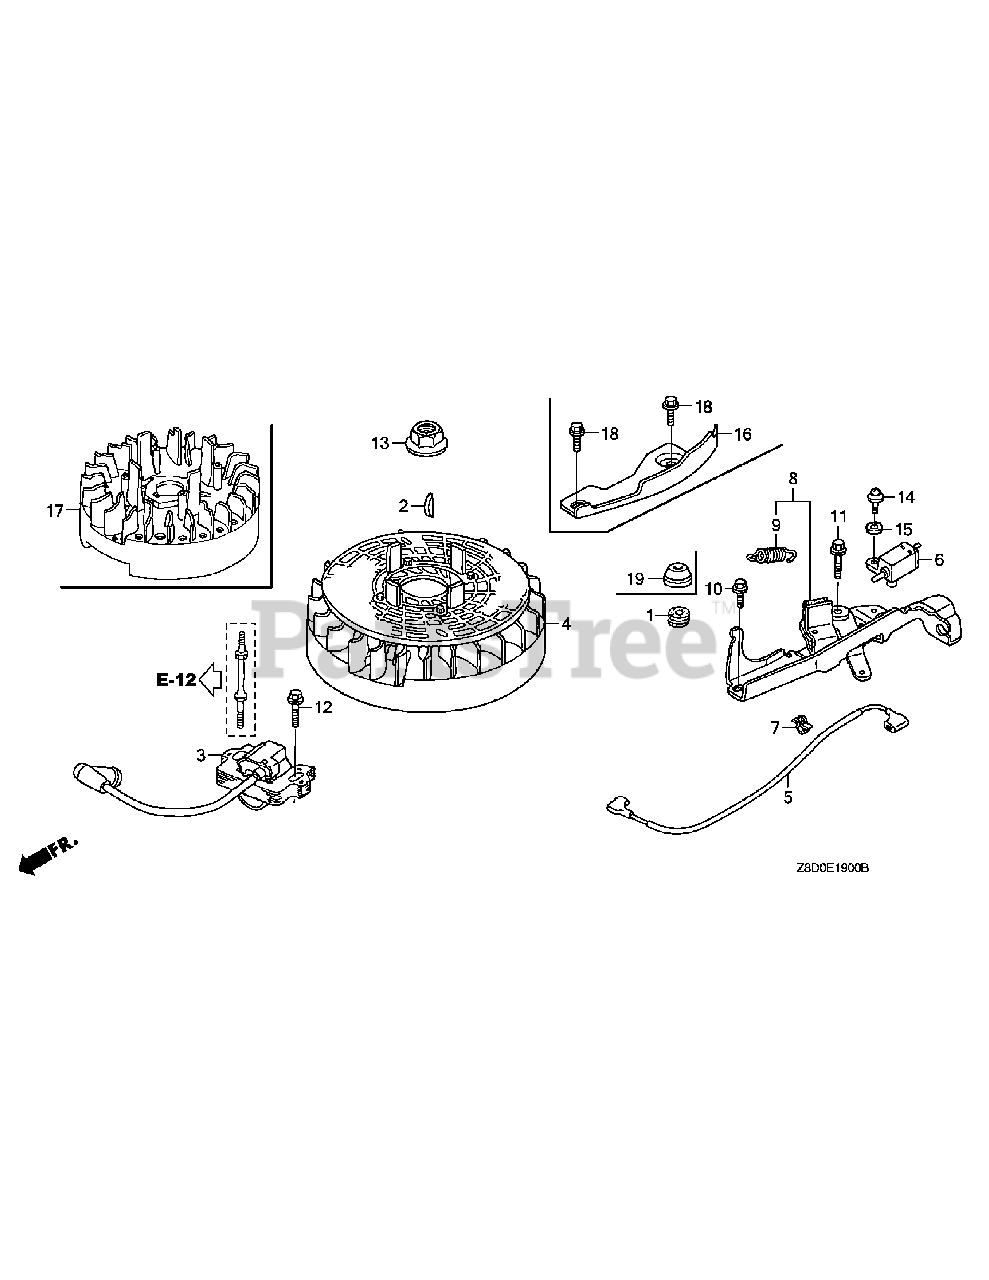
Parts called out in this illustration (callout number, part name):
1	Rear Cover Grommet A
2	Special Woodruff Key
3	Ignition Coil Assembly
4	Flywheel Assembly
5	Stop Switch Cord
6	Engine Stop Switch Assembly
7	Wire Holder (Fastex)
7	Cable Clip A, 3.8mm Black (Nifco)
8	Brake Sub Ass’y
9	Brake Lever Spring
10	Flange Bolt, 6 x 14 (CT200)
11	Flange Bolt, 6 x 23 (CT200)
12	Flange Bolt, 6 x 20 (CT200)
12	Flange Bolt, 6 x 23 (CT200)
13	Flange Nut, 14mm
14	Screw-Washer, 4 x 12
15	Plain Washer, 4mm
19	Brake Plate Grommet
